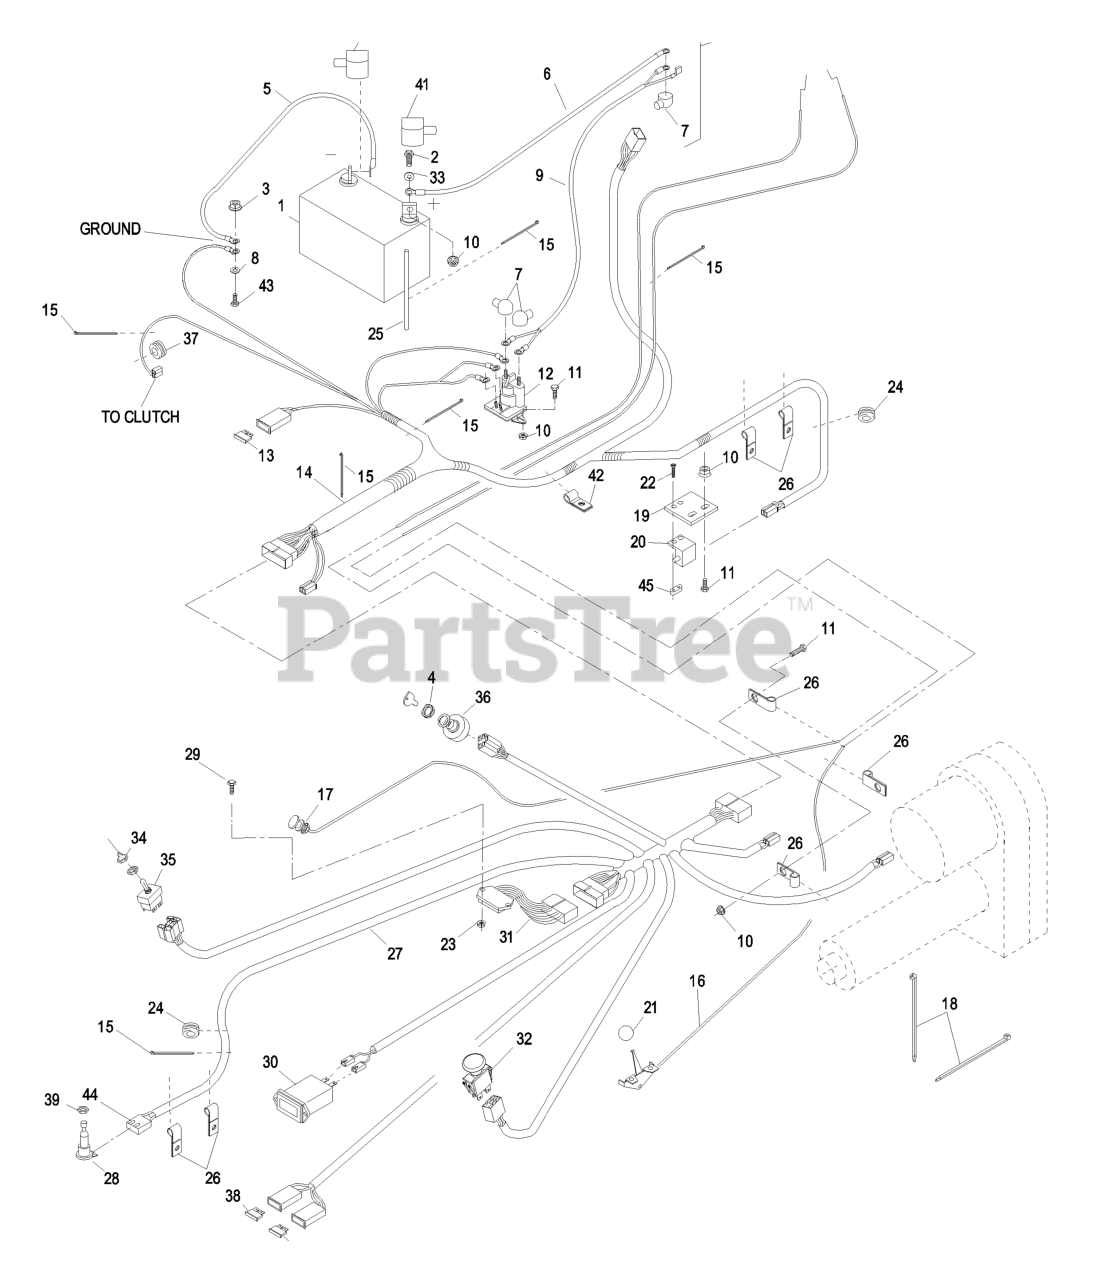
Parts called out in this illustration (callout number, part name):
2	SCREW-HH
4	NUT-SWITCH, IGNITION
5	WIRE-GROUND
7	INSULATOR-SOLENOID
8	WASHER-SPRING
11	SCREW-HH
13	FUSE-BLADE TYPE, 20 AMP
15	TIE-CABLE
16	THROTTLE CABLE ASM
17	CONTROL-CHOKE
18	TIE-PLASTIC
19	BRACKET,SAFETY SWITCH
20	SWITCH-OPEN, NORMALLY
21	KNOB-BALL
22	10-24 X 5/8 FLT HD MS
23	NUT-LOCK, NI
24	GROMMET
26	CLIP-LOOM
27	HARNESS,CONSOLE WIRING
28	SWITCH,PUSH BUTTON
30	METER-HOUR
31	MODULE,OPC
33	WASHER-FLAT
34	BOOT-SWITCH, TOGGLE
35	SWITCH-TOGGLE, DPDT
36	SWITCH,IGNITION
37	GROMMET
38	FUSE-BLADE TYPE, 30 AMP
41	INSULATOR, BATTERY -
42	CLIP-LOOM
43	SCREW-HH
44	CONNECTOR,PACKARD 2 WAY
45	PLATE-TAPPED
